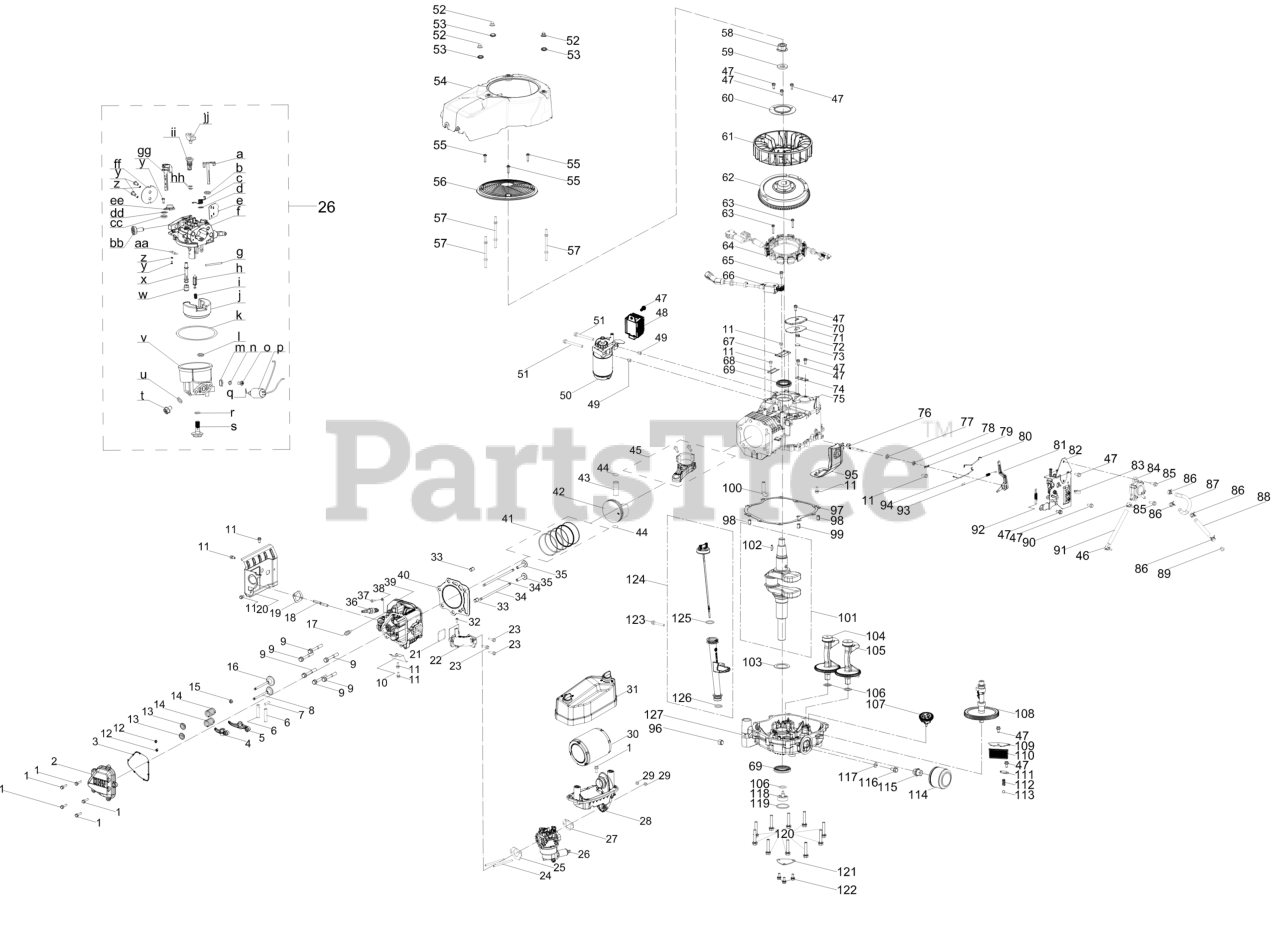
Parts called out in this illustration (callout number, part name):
1	BOLT M6-1 x 25 GR8.8
2	VALVE COVER
3	VALVE COVER GASKET
4	ROCKER ARM (EXHAUST)
5	ROCKER ARM (INTAKE)
6	ROCKER ARM SHAFT
7	CAMSHAFT PIN
8	EXHAUST VALVE
9	BOLT M10-1.25 x 70
11	BOLT M6-1 x 12 GR8.8
12	VALVE CAP
13	VALVE SPRING SEAT
14	VALVE SPRING
15	INTAKE VALVE SEAL
16	INTAKE VALVE
19	EXHAUST GASKET
20	SHROUD - LEFT SIDE
21	INTAKE PIPE RING
22	INTAKE PIPE
23	BOLT M6 x 22
24	STUD M6-1.00 x 92
25	INTAKE GASKET
26	CARBURETOR ASSEMBLY HY-8X90
27	AIR FLTER GASKET
28	INTAKE MANIFOLD
30	AIR FILTER W/PREFILTER
31	AIR FILTER COVER
32	SELF TAPPING SCREW 4.8 x 16
34	SINGLE PUSH ROD
36	SPARK PLUG
37	BOLT M5-.8 x 10
38	FLAT WASHER: 5.3 x 10 x 1
39	CYLINDER HEAD
40	CYLINDER HEAD GASKET
41	PISTON RING SET
43	PISTON PIN
44	PISTON PIN SNAP RING
45	CONNECTING ROD ASSEMBLY
47	BOLT M6-1 x 14 GR8.8
48	REGULATOR ASSEMBLY
50	STARTER
51	BOLT M8-1.25 x 80
52	ACORN NUT
55	BOLT 5.5 x 25
56	DEBRIS SHIELD
58	NUT M20 x 1.5
59	WASHER 20.5 x 5 x 40
60	VANE PLATE
61	COOLING FAN
63	BOLT M5 x 28
64	CHARGING COIL
65	BOLT-M6-1 x 28 GR8.8
66	IGNITION COIL ASSEMBLY
67	WIRE PLATE
68	BREATHER SCREEN
69	OIL SEAL 38 x 58 x 8
70	BREATHER COVER
71	BREATHER COVER GASKET
72	BREATHER VALVE SPRING
73	BREATHER VALVE
75	Crankcase
76	GOVERNOR GEAR SHAFT
77	WASHER 8 x 0.8 x 16
78	GOVERNOR SEAL
79	GOVERNOR SHAFT CLIP
80	CHOKE LINKAGE
81	GOVERNOR LEVER
82	THROTTLE BRACKET ASSEMBLY
83	FUEL LINE SUPPORT CLAMP
85	BOLT M6-1 x 18 GR8.8
86	HOSE CLAMP
87	BREATHER HOSE
88	FUEL HOSE (6.3 x 12.5 x 100)
91	FUEL HOSE (6.3 x 12.5 x 180)
92	GOVERNOR SPRING
93	THROTTLE LINKAGE SPRING
94	THROTTLE LINKAGE
95	SHROUD - RIGHT
96	ENGINE PLUG 3/8 NPT
97	CRANKCASE COVER GASKET
98	DOWEL PIN
99	DOWEL PIN
100	VENTING HOSE
101	CRANKSHAFT ASSEMBLY
102	FLYWHEEL KEY
103	WASHER 38.3 x 54 x 1
104	BALANCE SHAFT (LH)
105	BALANCE SHAFT (RH)
106	WASHER 17.2 x 26 x 1
107	GOVERNOR GEAR ASSEMBLY
109	FILTER COVER
110	FILTER SCREEN
111	PRESSURE RELEASE COVER
112	PRESSURE RELEASE SPRING
113	OIL PUMP STEEL BALL
114	ENGINE OIL FILTER
115	SCREW JOINT OIL FILTER ADAPTER
116	BOLT M8 x 15
117	OIL DRAIN PLUG WASHER
118	OIL PUMP ASSEMBLY
120	BOLT M8 x 45
121	OIL SEPARATOR
122	SCREW M6-1 x 16
123	BOLT M6-1 x 45 CL5.8
124	DIPSTICK ASSEMBLY
127	CRANKCASE COVER W/GOVERNOR
